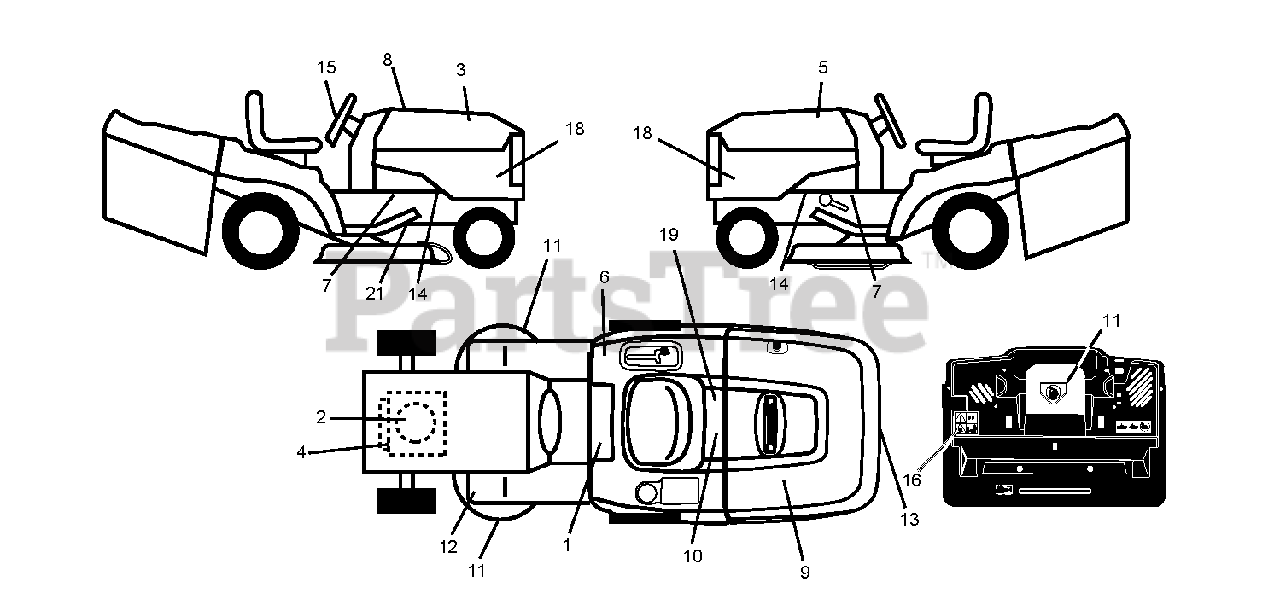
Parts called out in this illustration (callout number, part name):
10	DECAL BTRY SYMBOLS
11	DECAL.INTERNATIONL.CUTFINGER
19	DECAL PARK BRAKE
